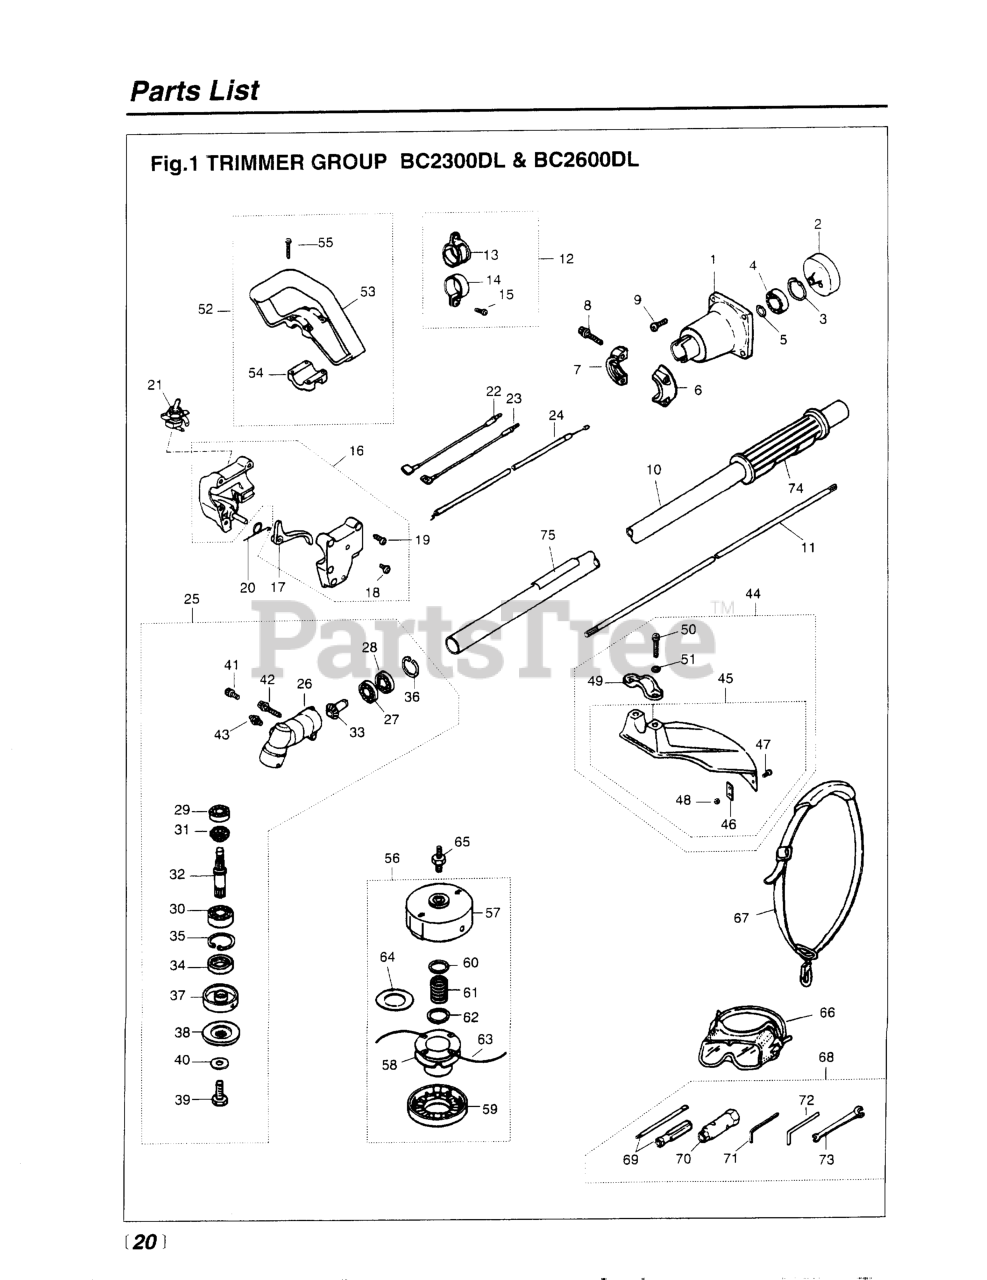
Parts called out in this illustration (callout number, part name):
3	RING, SNAP, M28 x 1.2
4	BEARING
5	RING, SNAP (RPLS 3130-13270)
6	CLAMP, LEFT
7	CLAMP, RIGHT
8	BOLT
9	BOLT, M6 x 20
12	HANGER COMPLETE
13	HANGER
14	CLAMP
15	SCREW, M5 x 25
17	LEVER, THROTTLE
18	SET SCREW, ANTI-ROTATION
19	SCREW
20	SPRING, THROTTLE TRIGGER
21	SWITCH, STOP
22	CORD, RED (LEAD WIRE)
23	CORD, BLACK (LEAD WIRE)
24	CABLE COMP (RPLS 6460- )
25	GEARCASE ASSEMBLY
26	GEARCASE
27	BEARING
28	BEARING
29	BEARING
30	BEARING
31	GEAR
33	PINION
34	SEAL, OIL
35	RING, SNAP
36	RING, SNAP
37	HOLDER (A)
38	HOLDER (B)
40	WASHER
41	BOLT, M5 x 12
42	BOLT, M5 X 25
43	FITTING, GREASE
44	GUARD ASSEMBLY
46	BLADE
47	SCREW, M5 x 12
48	NUT
49	CLAMP
50	BOLT, M6 x 1.30
51	WASHER, M6 X 15
52	HANDLE ASSEMBLY
53	HANDLE
54	CLAMP
55	SCREW, M5 x 35
56	4
60	PLATE, LARGE
62	PLATE, SMALL
63	CORD
64	SPACER
65	ARBOR, 8MM
66	GOGGLE
67	SHOULDER STRAP ASSY
68	TOOL SET
69	SCREWDRIVER
71	WRENCH (TOOL)
72	BAR
73	SPANNER, 8 X 10 (RPLS 2540- )
75	LABEL, BC2300/2600DL
